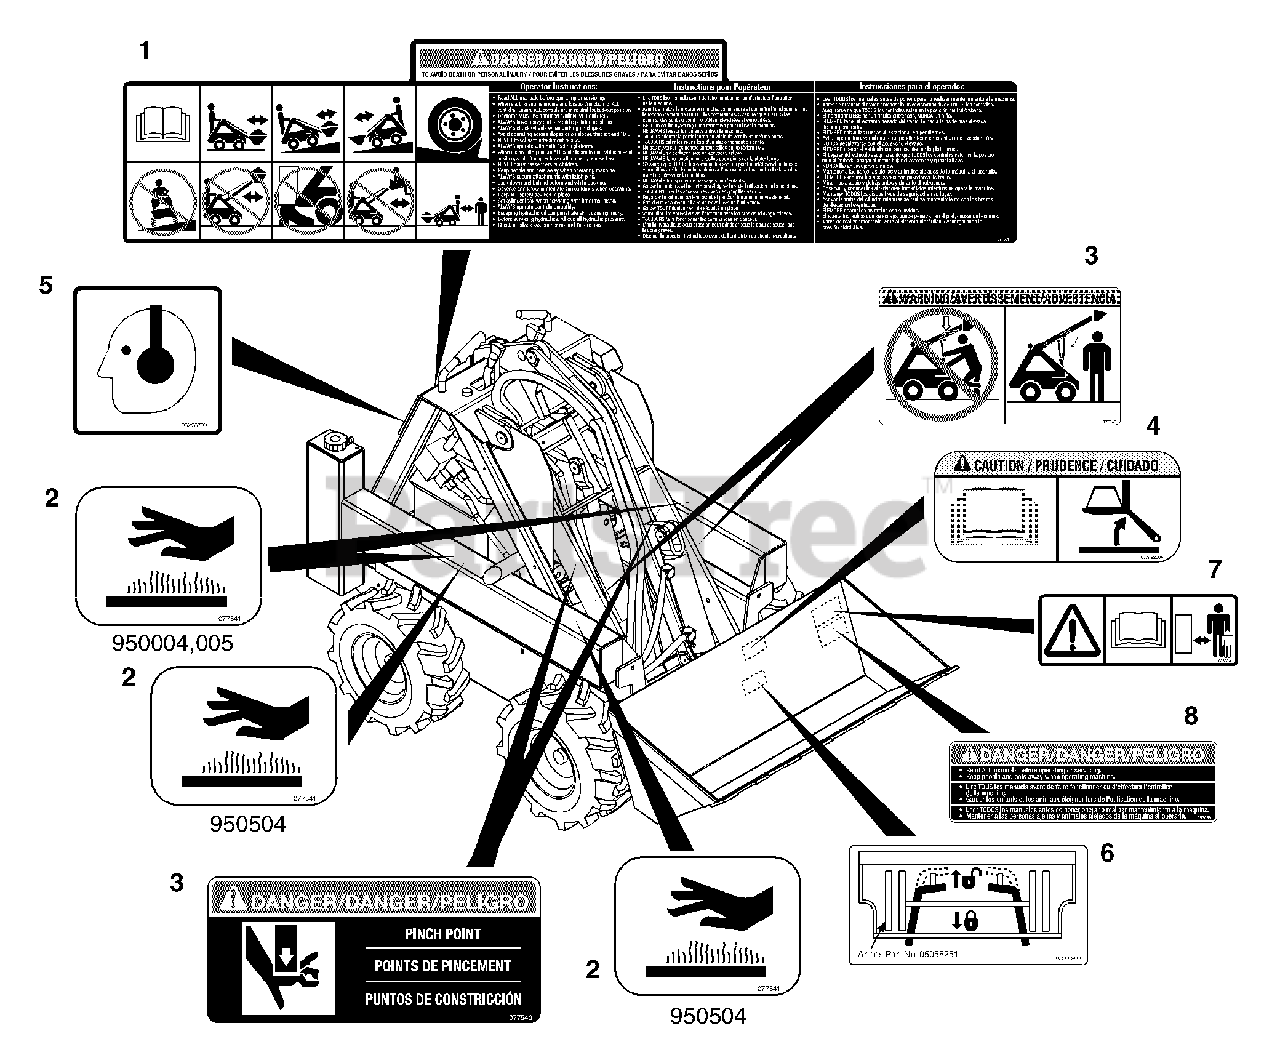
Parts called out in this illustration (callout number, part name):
1	Decal, Operator Safety Instruction
2	Decal, Hot Surface
3	Set, Decal
4	Decal, Weight Capacity
5	Decal, Ear Protection
6	Decal, Attachment Locking Pin
7	Decal, Danger Attachment: Universal
8	Decal, Danger Attachment Universal
